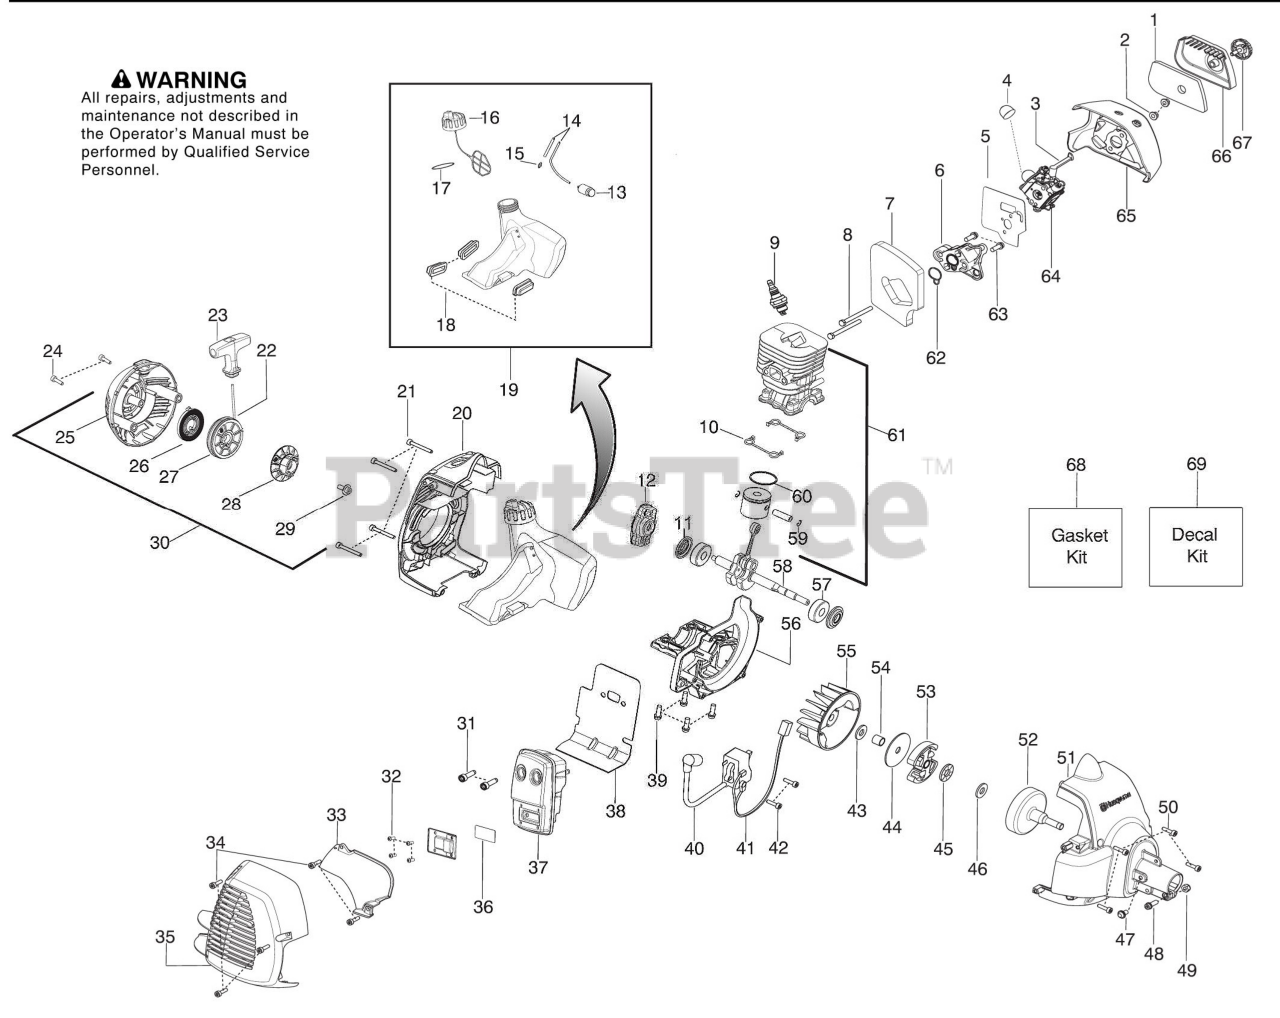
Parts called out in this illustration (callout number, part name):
2	Nut - Carb. Screw
3	Lever - Choke
4	Bulb - Purge
5	Kit - Carb. Gasket
6	Adaptor - Carb.
7	Foam – Gasket
9	Plug - Spark (RCJ-8Y)
10	Seal – Cylinder
11	Seal – Crankshaft
12	Assy - Starter Pawl
13	Assy - Fuel Filter
14	Kit - Fuel Line
15	Fitting - Fuel line
16	Assy - Cap w/ret.
17	O-ring - Fuel Cap
18	Isolator - Fuel Tank
19	Kit - Fuel Tank Assy.
20	Shroud - Rear
22	Kit - Rope
23	Handle - Starter
25	Hsg. - Starter w/eyelet
26	Kit - Spring
27	Kit - Starter Pulley
28	Pulley-Driver
30	Assy - Starter Hsg.
31	Bolt - Muffler
32	Screw
33	Shield - Heat
35	Guard - Muffler
36	Kit - Spark
37	Assy - Muffler
38	Gasket - Paper Met.
41	Assy - Leadwire
44	Washer - Clutch
45	Bearing - Thrust
46	Washer - Thrust
51	Assy - Fan Housing
52	Assy - Clutch Drum
53	Assy - Clutch Assy
56	Crankcase - Cast
58	Assy - Crankshaft
59	Retainer - Piston Pin
60	Ring - Piston
61	Kit - Piston/Cyl.
62	Seal – adaptor
64	Kit - Carb.
65	Airbox
66	Cover - Air Box
67	Assy - Knob
68	Kit - Gasket
69	Kit - Decal
